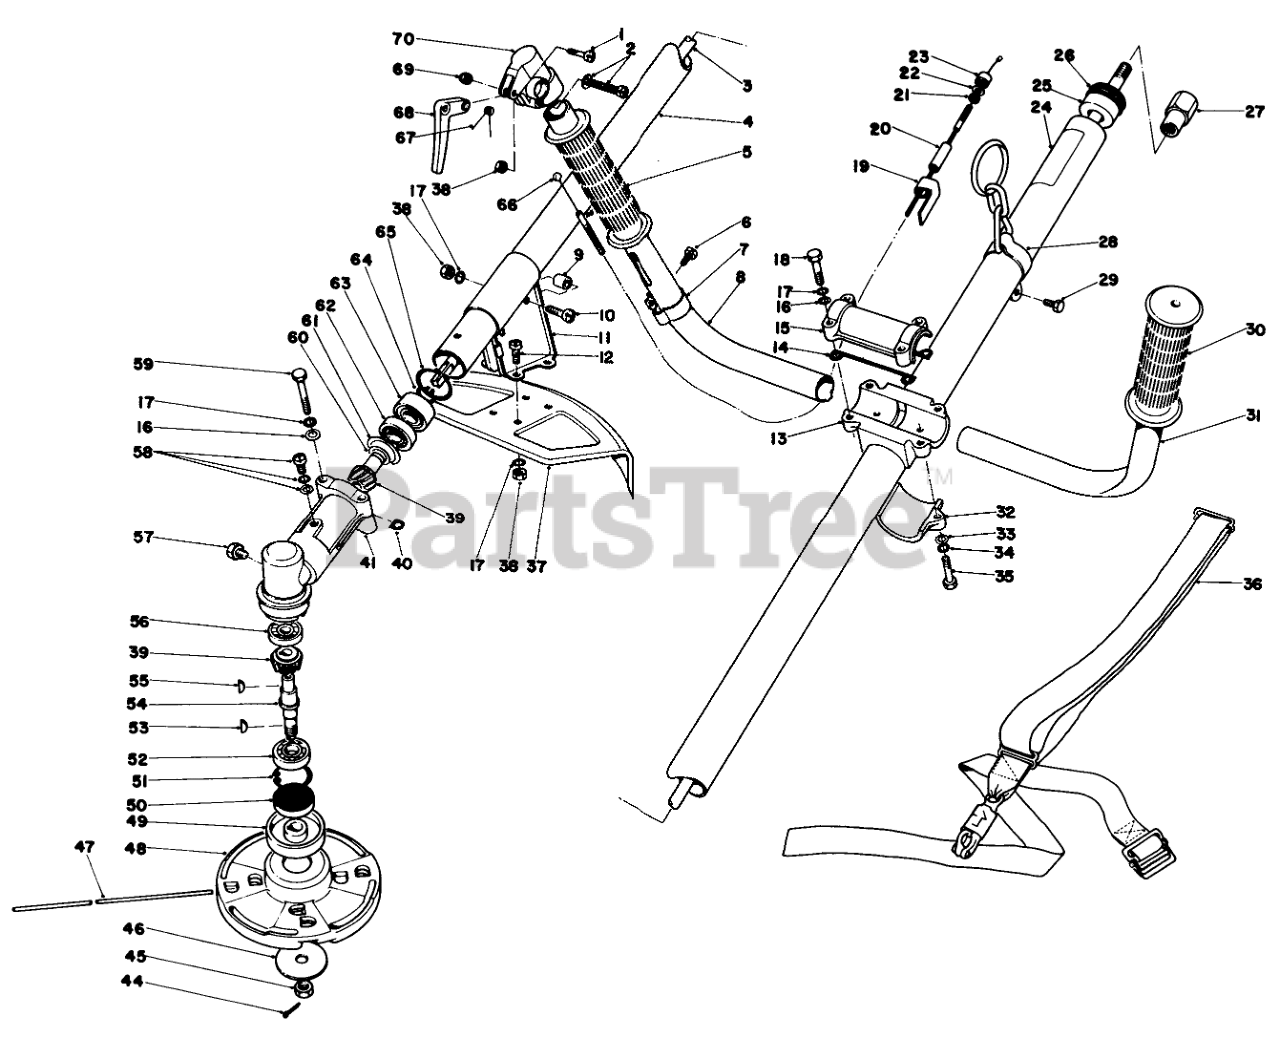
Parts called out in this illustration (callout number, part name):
1	Screw
2	Screw W/washer
3	Drive Shaft
4	Housing, Drive Shaft
5	Right Hand Grip
6	Screw
8	Handle
9	Spacer
10	Screw
11	Bracket-Head Guard
12	SCREW
13	Body, Handle Bracket
14	Spacer
15	Handle Bracket, Upper
16	WASHER
17	Washer
19	Clamp
22	Washer
23	Locknut
24	Decal Warning
25	Bushing
26	O-Ring
27	Coupler
28	Swivel Hook
30	LH GRIP
31	Handle
32	Handle Bracket, Lower
33	Washer
34	Washer
36	Shoulder Strap Deluxe
37	Shield
38	Nut
39	Gear Set
40	Spacer
41	Gear Housing
44	Split Pin
44	1/16 X 1 LG COTTER PIN
46	WASHER
47	Cotter Pin
48	Cutter Head
49	Plate-Blade Fixing
50	Oilseal
51	Circlip
52	Ball Bearing
53	Woodruff Key
54	Shaft-PTO
55	Woodruff Key
56	Ball Bearing
58	SCREW
60	Washer
61	Washer
62	Ball Bearing
63	Ball Bearing
64	Circlip
65	Circlip
66	THROTTLE CABLE
67	Return Spring
68	THROTTLE LEVER
70	Bracket-Throttle Trigger
